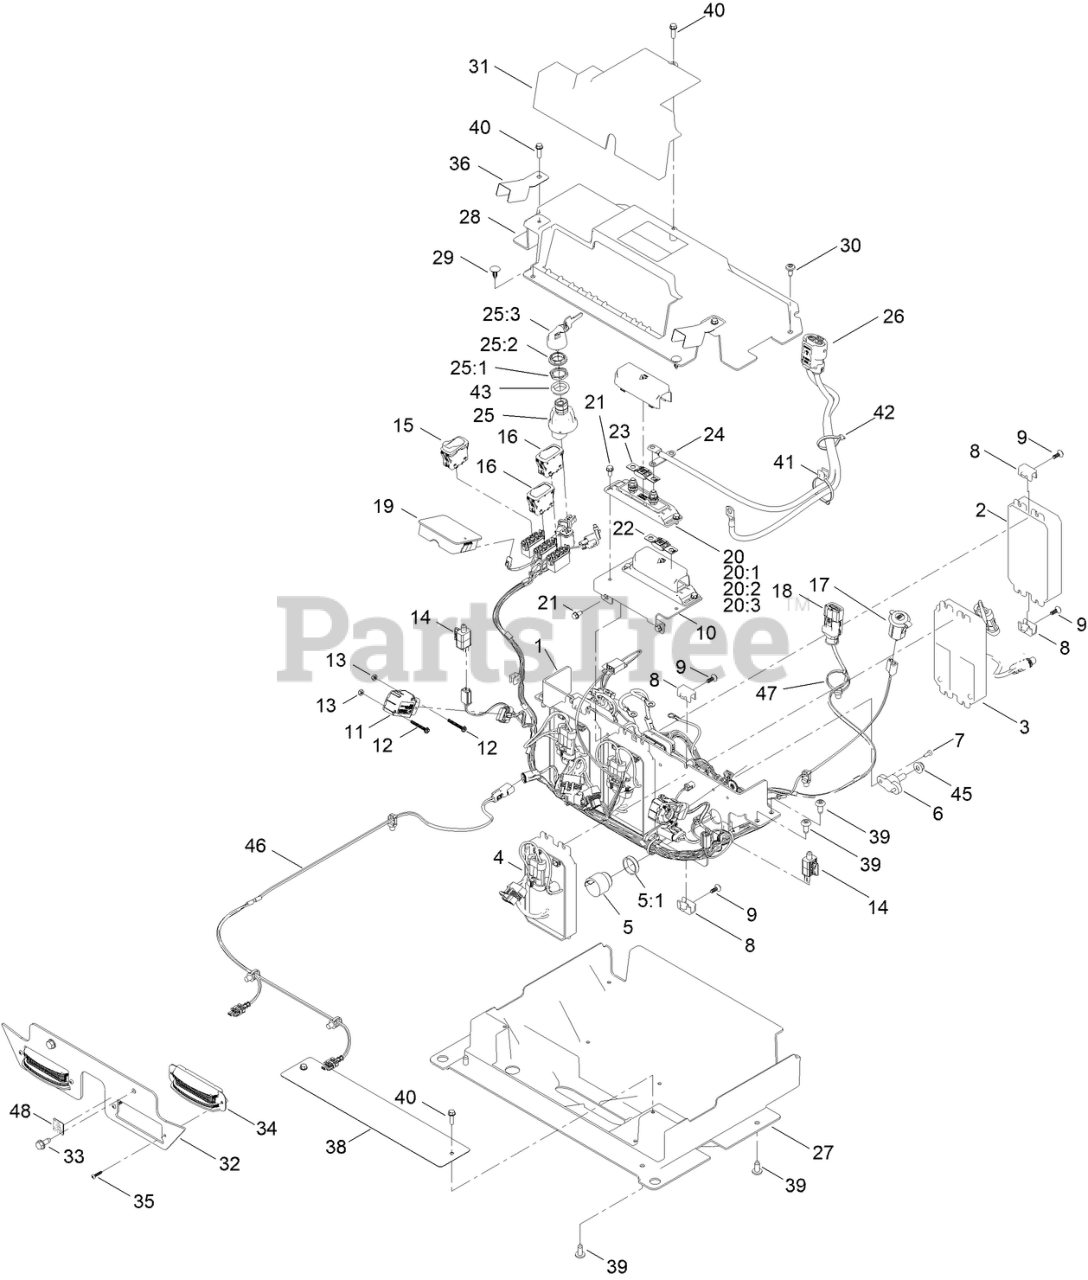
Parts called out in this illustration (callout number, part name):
1	MOUNT-CONTROLLERS
2	CONTROLLER-MASTER
3	CONTROLLER-TRACTION
4	CONTROLLER-DECK
5	AUDIO ALARM ASM
5:1	NUT-PLASTIC, KNURLED
6	BLOCK-JUNCTION
7	SCREW-FORMING, THREAD
8	CLIP-CONTROLLER
9	SCREW-DELTA POINT
10	MOUNT-HOLDER, FUSE
11	SENSOR
12	SCREW-HWH
13	NUT-HEX NI
14	SWITCH
15	SWITCH-ROCKER, ON-NONE-ON
16	SWITCH-ROCKER ON- NONE- ON
17	PORT-POWER, USB
18	HARNESS-WIRE, 3 BLADE MAIN
19	DISPLAY
20	HOLDER-FUSE
20:1	WASHER-LOCK
20:2	WASHER-FLAT
20:3	NUT-HEX
21	SCREW-HWH
22	FUSE-150A
23	FUSE-100 AMP
24	BUSBAR-2, SWITCH
25	SWITCH-IGNITION, SUNS
25:1	NUT-HEX
25:2	NUT-FACE, M22 (PLASTIC)
25:3	SET-KEY, IGNITION
26	HARNESS-WIRE, POWER CABLE
27	COVER-BOTTOM
28	COVER-CONTROLLER
29	PLUG-PLASTIC
30	SCREW-SHOULDER
31	COVER-OUTER
32	MOUNT-HEAD LIGHTS
33	SCREW-HWHTF
34	ASM-LIGHT,LED
35	SCREW-PPH
36	COVER-SENSOR
38	COVER-WIRE
40	SCREW-PLASTITE, HWH
41	CLIP-EDGE
42	TIE-CABLE
43	ADAPTER-SWITCH, KEY
45	NUT-HF, NI
46	HARNESS-WIRE, LED LIGHTS
47	CLIP-TIE
